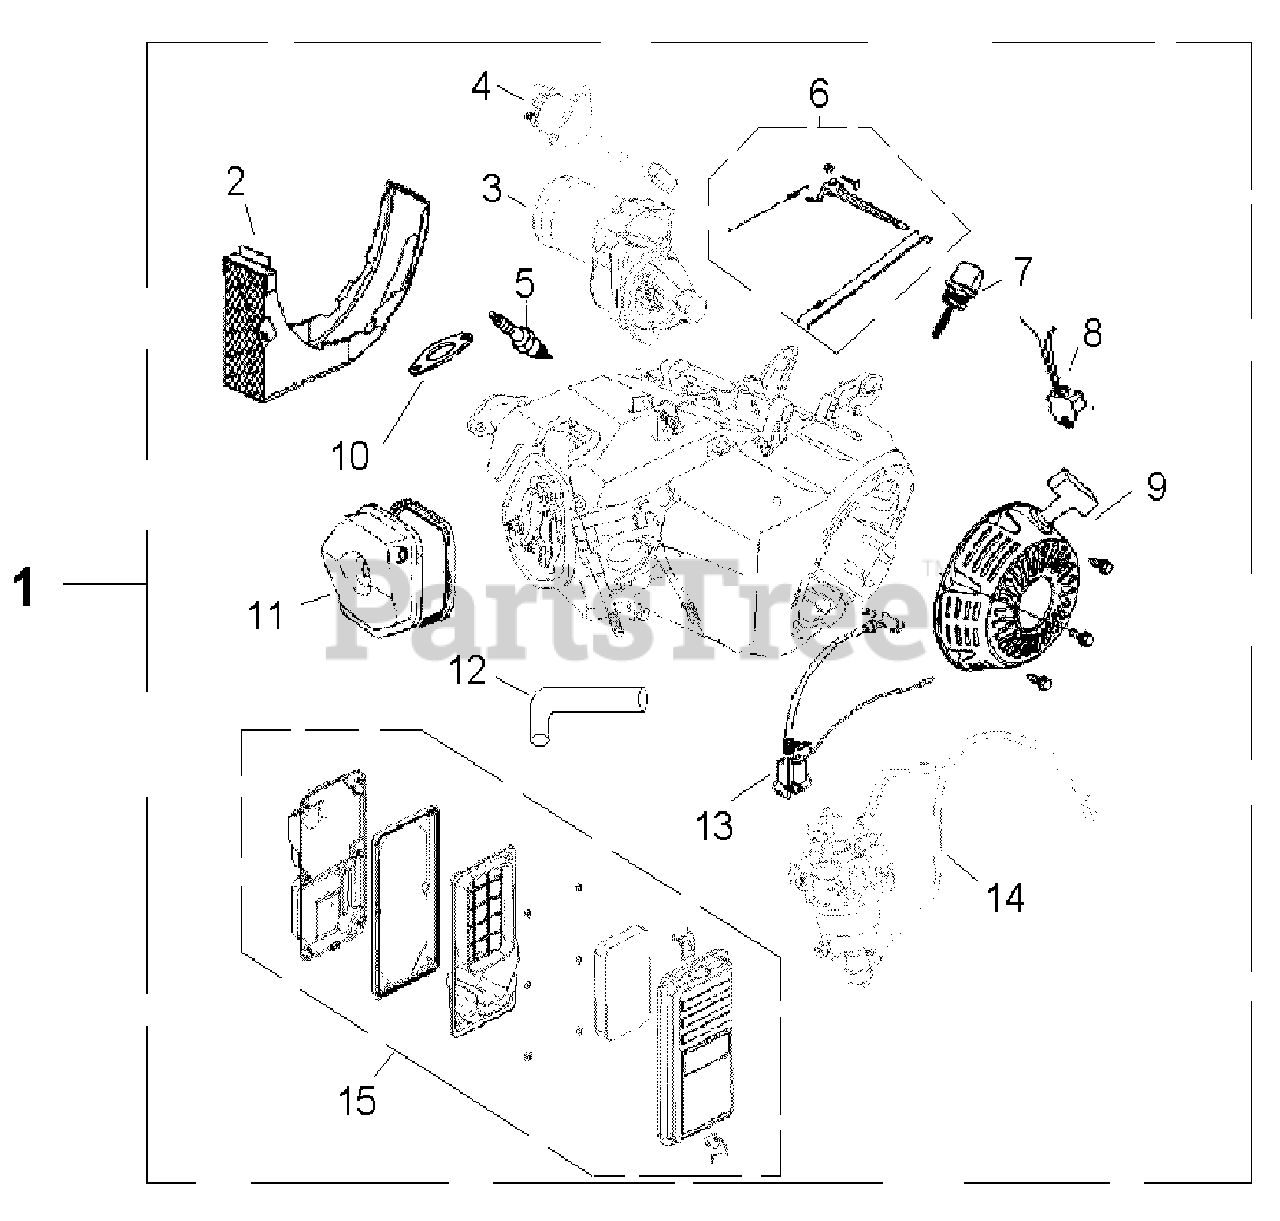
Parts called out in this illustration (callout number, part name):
3	STARTER MOTOR
4	CONTACTOR ASSY.
6	CONTORL ASSY.
7	CAP COMP., OIL FILLER
8	ALART UNIT,OIL
9	STARTER ASSY.
10	GASKET, EX., PIPE
11	COVER COMP. HEAD
13	COIL ASSY., IGNITION
14	CARBURETOR ASSY.
